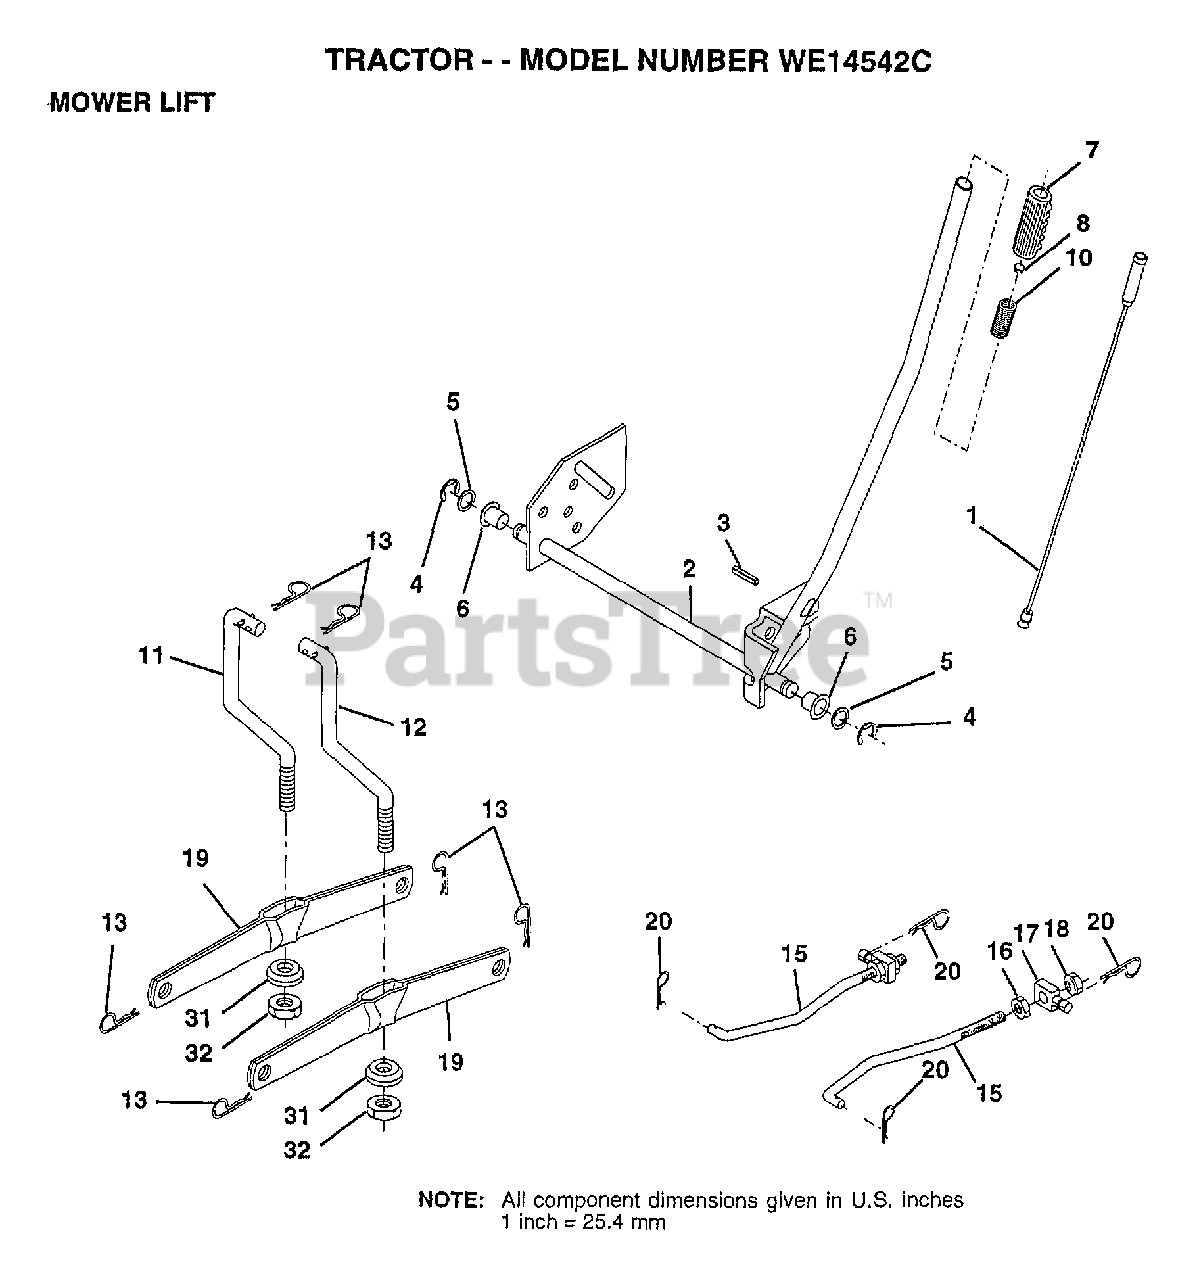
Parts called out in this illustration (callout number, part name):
1	WIRE ASM
2	SHAFT.LIFT.ASM.RH
3	PIN-GROOVE LT
5	WASHER
6	NYLON BEARING
7	GRIP
15	LINK.FRONT
16	NUT
17	TRUNION
18	NUT.LK.W/WSH.1/2.
19	ARM SUSP REAR
20	RETAINER.SPRING
31	BEARING PVT LH
32	NUT.CROWNLOCK.3/8
